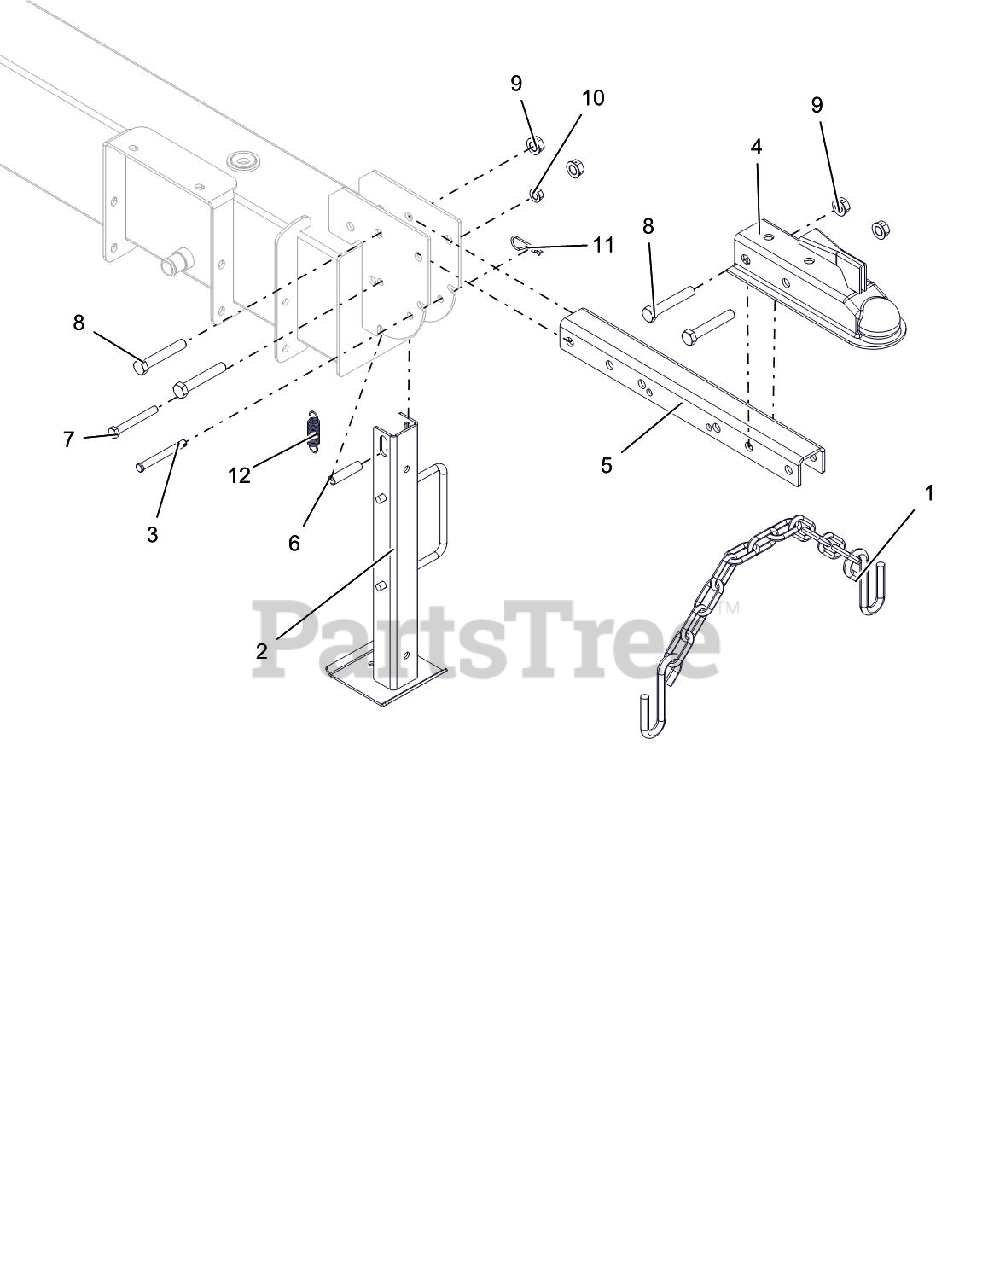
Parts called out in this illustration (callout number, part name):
1	CHAIN, SAFETY
2	WLDMT, JACK STAND
3	PIN-CLEV .371X3.25 YWZC
4	HITCH, BALL-2"
5	BAR, HITCH
6	SPCR, WHEEL .385X.500X2.00
7	@BLT-HEX .38-16X3.00 GR5 YWZC
8	@BLT-HEX .50-13X3.00 GR5 YWZC
9	NUT-LK-CTR-FLG .50-13 YWZC
10	@NUT-LK-TOP-FLG .38-16 YWZC
11	HAIRPIN, #7 CLIP .094X2.31 YWZ
12	SPRG, TENSION .063X.625X2.50
